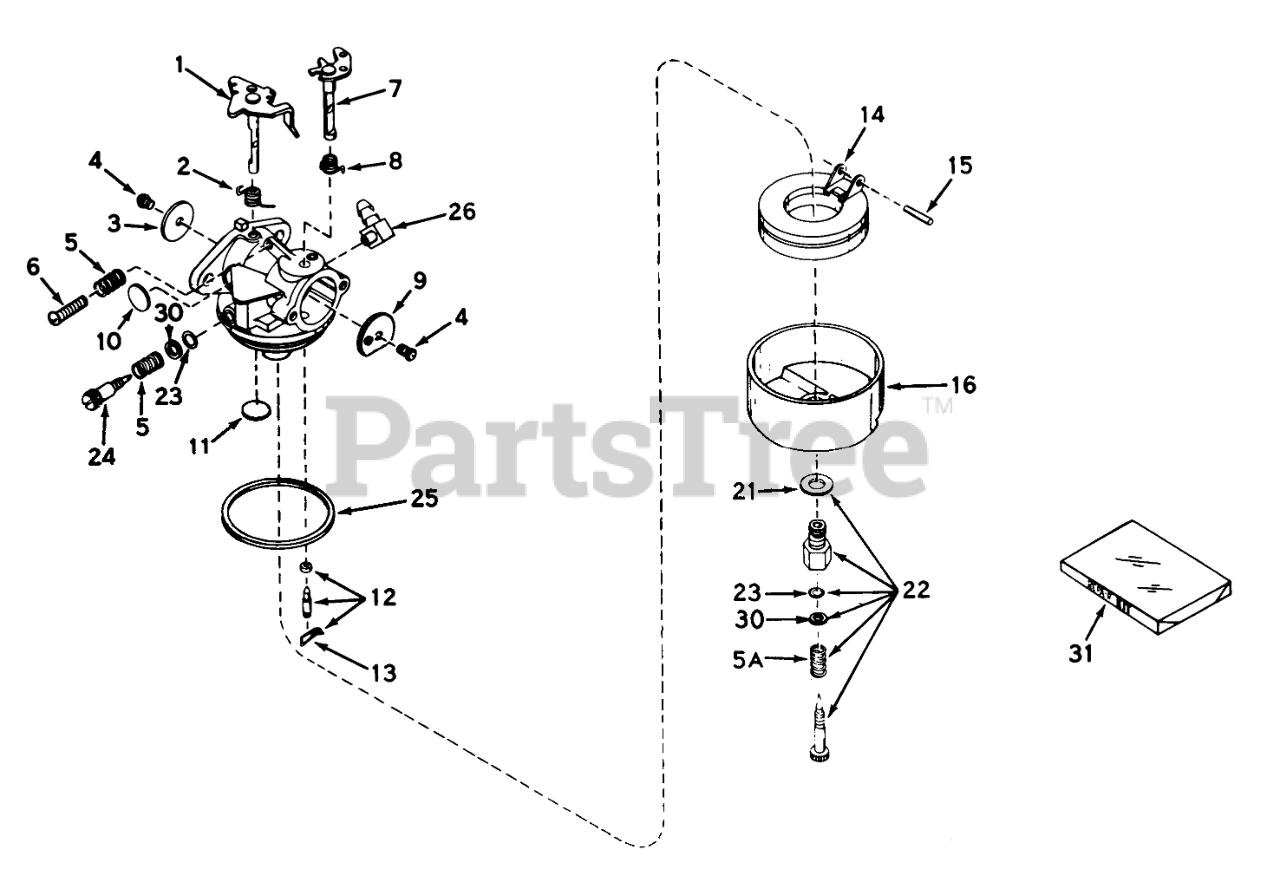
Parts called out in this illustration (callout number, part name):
1	Shaft/Lever-Throttle
2	Spring, Throtte Return
3	Shutter-Throttle
4	Screw-Shutter
5	Spring-Tension
6	Screw-Throttle Crack Screw / Idle Speed
7	Shaft& Lever Assy., Choke
8	Spring, Choke return
9	Shutter-Choke
10	Plug-Welch, Idle Mixture Well
11	Plug-Welch, Atmospheric Vent
12	Inlet Needle, Seat & Clip Assy. (Incl. No. 13)
13	Clip-Spring
14	Float,Carburetor
15	Shaft-Float
16	Bowl-Float (no drain)
21	Washer-Bowl Nut
22	Adjustment Screw Assy., Main (Incl. Nos. 5A, 21, 23 & 30)
23	"O"Ring
24	Screw, Idle Adj.
25	O Ring-Bowl, Float
26	Fitting-Fuel Inlet
31	Repair Kit
